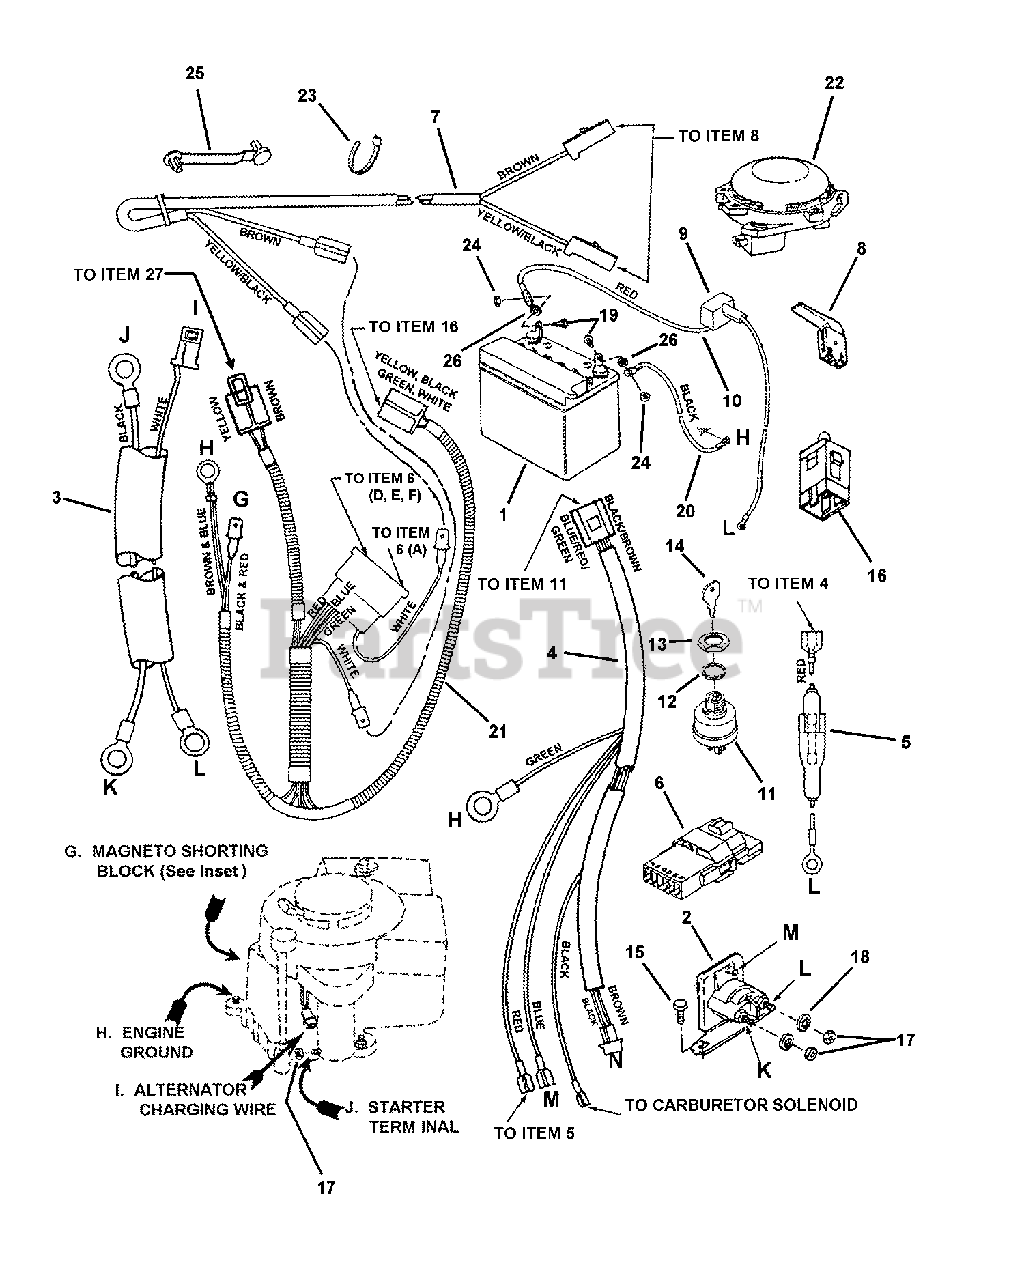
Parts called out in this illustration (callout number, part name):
1	KIT, Battery, 12V, U-1-7RS, 220CCA Dry Charge Snapper No Spill
2	SOLENOID, Super-Trombetta
3	HARNESS, Starter Wiring (Briggs)
4	HARNESS, Ignition Wiring (Briggs)
5	HOLDER, Fuse (Includes Fuse)
6	INTERLOCK MODULE, Briggs & Kohler
7	HARNESS (Deck Interlock Wiring)
8	SWITCH, Deck Interlock (NO)
9	COVER, Battery Cable
10	WIRE, Positive (Red, 17" long)
11	SWITCH, Ignition-Afterfire Solenoid
12	WASHER, 5/8" Internal Tooth Lock
13	NUT, 5/8-32 Hex
14	IGNITION KEY, Pair
15	SCREW, 1/4-20 x 1/2" Hex Washer Self-Tap
16	SWITCH, Operator Presence Control (OPC) Traction (NC/NO)
17	NUT, 1/4-20 Hex, GR 5 or B
18	WASHER, 1/4" Internal Tooth Lock
19	SCREW, 1/4-20 x 5/8" Hex Head Cap, GR 5
20	WIRE, Negative, Black (15" long)
21	HARNESS, Operator Presence Control (OPC) Wire
22	SWITCH, Seat (NC)
23	CABLE TIE, 7"
24	NUT, 1/4-20 Hex Center Lock, GR 5 or B
25	CABLE TIE
26	RETAINER, 1/4" Bolt
